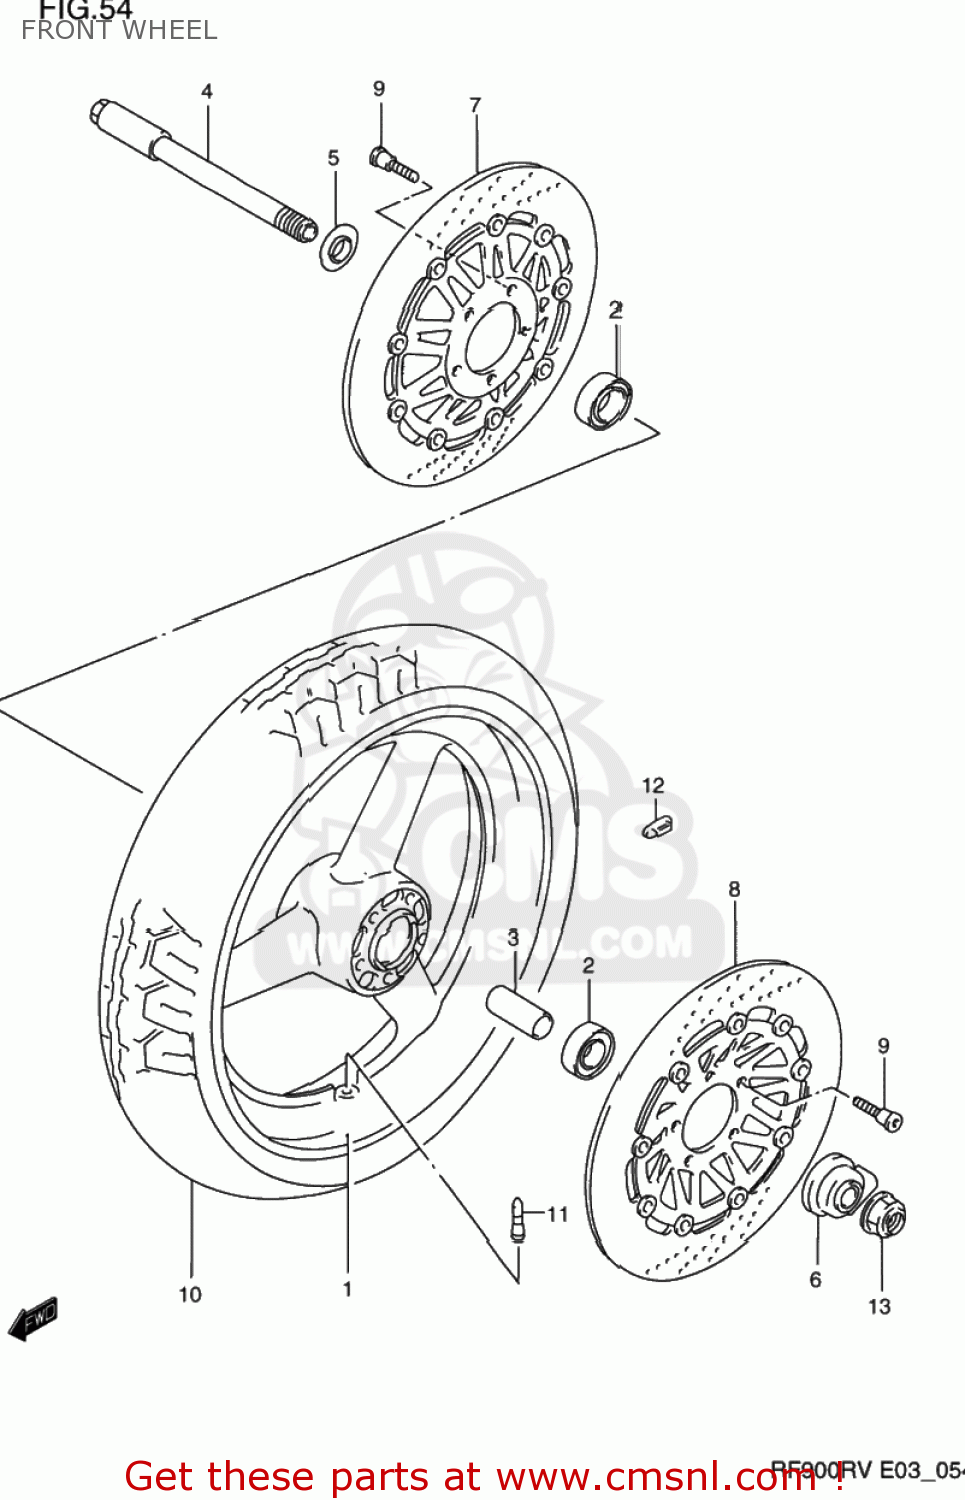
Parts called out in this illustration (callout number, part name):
1	WHEEL,FRONT (MT3.50X17)
2	BEARING
3	SPACER(20.8X27.2X74)
4	AXLE,FR
5	SPACER,FR HUB BEARING,R
6	BOX ASSY,SPEEDOMETER GEAR
7	DISC,FR BRAKE,R
8	DISC,FR BRAKE,L
9	BOLT 8X33
10	TIRE,FRONT 120/70 ZR17
11	VALVE ASSEMBLY,WHEEL,TR412
12	BALANCER,WHEEL (10G)
13	NUT
